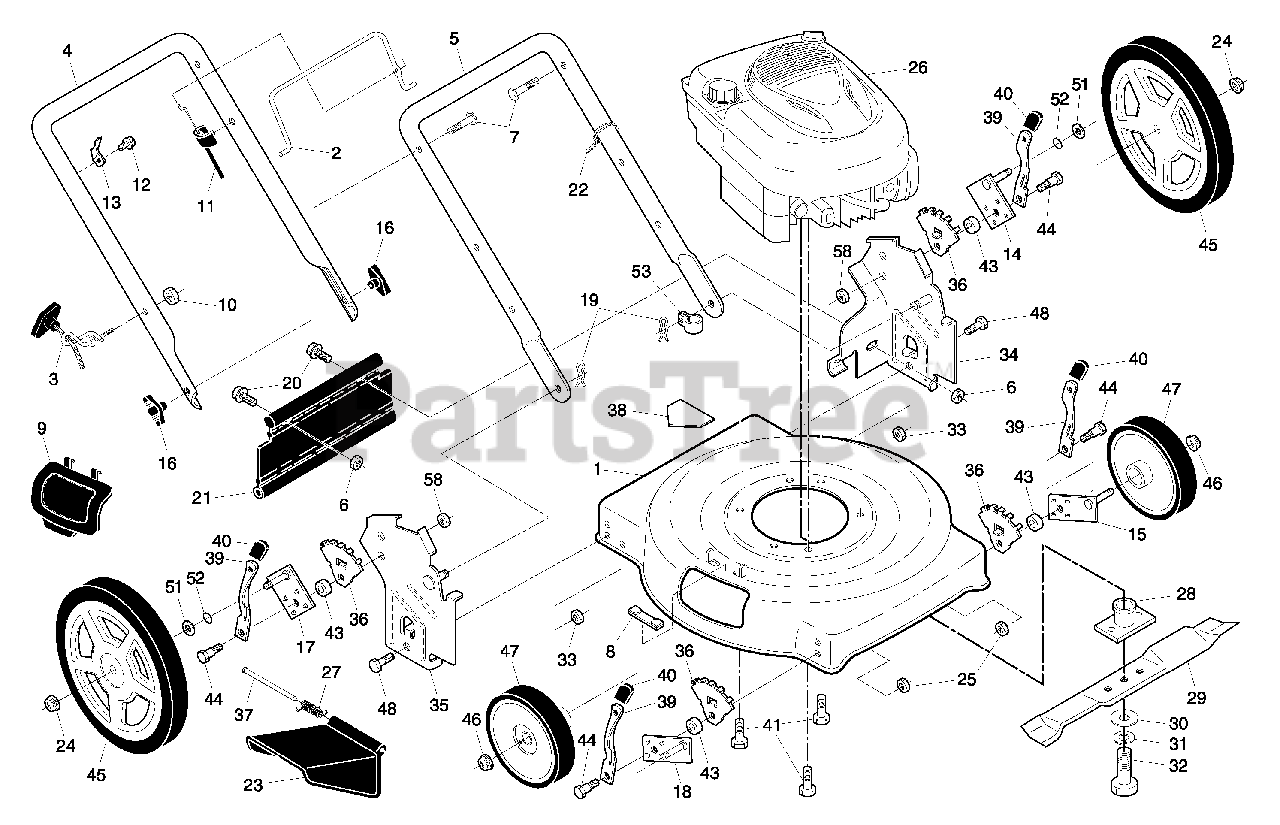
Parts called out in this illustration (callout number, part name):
1	Lawn Mower Housing
2	Control Bar
3	Rope Guide
4	Upper Handle
5	Lower Handle
6	Locknut, Hex 1/4-20
7	Handle Bolt 5/16-18
8	Clip, Closeout
9	Mulcher Plate
10	Nut, Hex 1/4-20
11	Engine Zone Control Cable
12	Hex Washer Head Screw #10-24 x 1/2
13	Up-Stop Bracket
14	Axle Arm Assembly, Rear, LH
15	Axle Arm Assembly, Front, LH
16	Knob, Handle
17	Axle Arm Assembly, Rear, RH
18	Axle Arm Assembly, Front, RH
19	Hairpin Cotter
20	Screw, Hex Cap Head 1/4-20
21	Rear Deflector
22	Wire Tie
23	Discharge Guard
24	Nut, Hex, Flangelock 3/8-16
25	Nut, Hex, Flangelock 5/16-18
27	Torsion Spring
28	Blade Adapter
29	22" Blade
30	Hardened Washer
31	Helical Lockwasher 3/8
32	Screw, Hex Head, Grade 8, 3/8-24 x 1-3/8
33	Nut, Hex, Nylock 5/16-18
34	Handle Bracket, LH
35	Handle Bracket, RH
36	Wheel Bracket Adjuster
37	Hinge Rod
38	Danger Decal
39	Selector Spring
40	Selector Knob
41	Screw, Hex Head, Threaded, Rolled 3/8-16 x 1
43	Spacer
44	Shoulder Bolt 5/16-18
45	Wheel & Tire Assembly, Rear, 12"
46	Nut, Hex
47	Wheel & Tire Assembly, Front, 8"
48	Bolt, Hex Head 5/16-18
51	Washer, Flat 3/8
52	O-Ring
53	Clip, Cable
58	Nut, Hex
